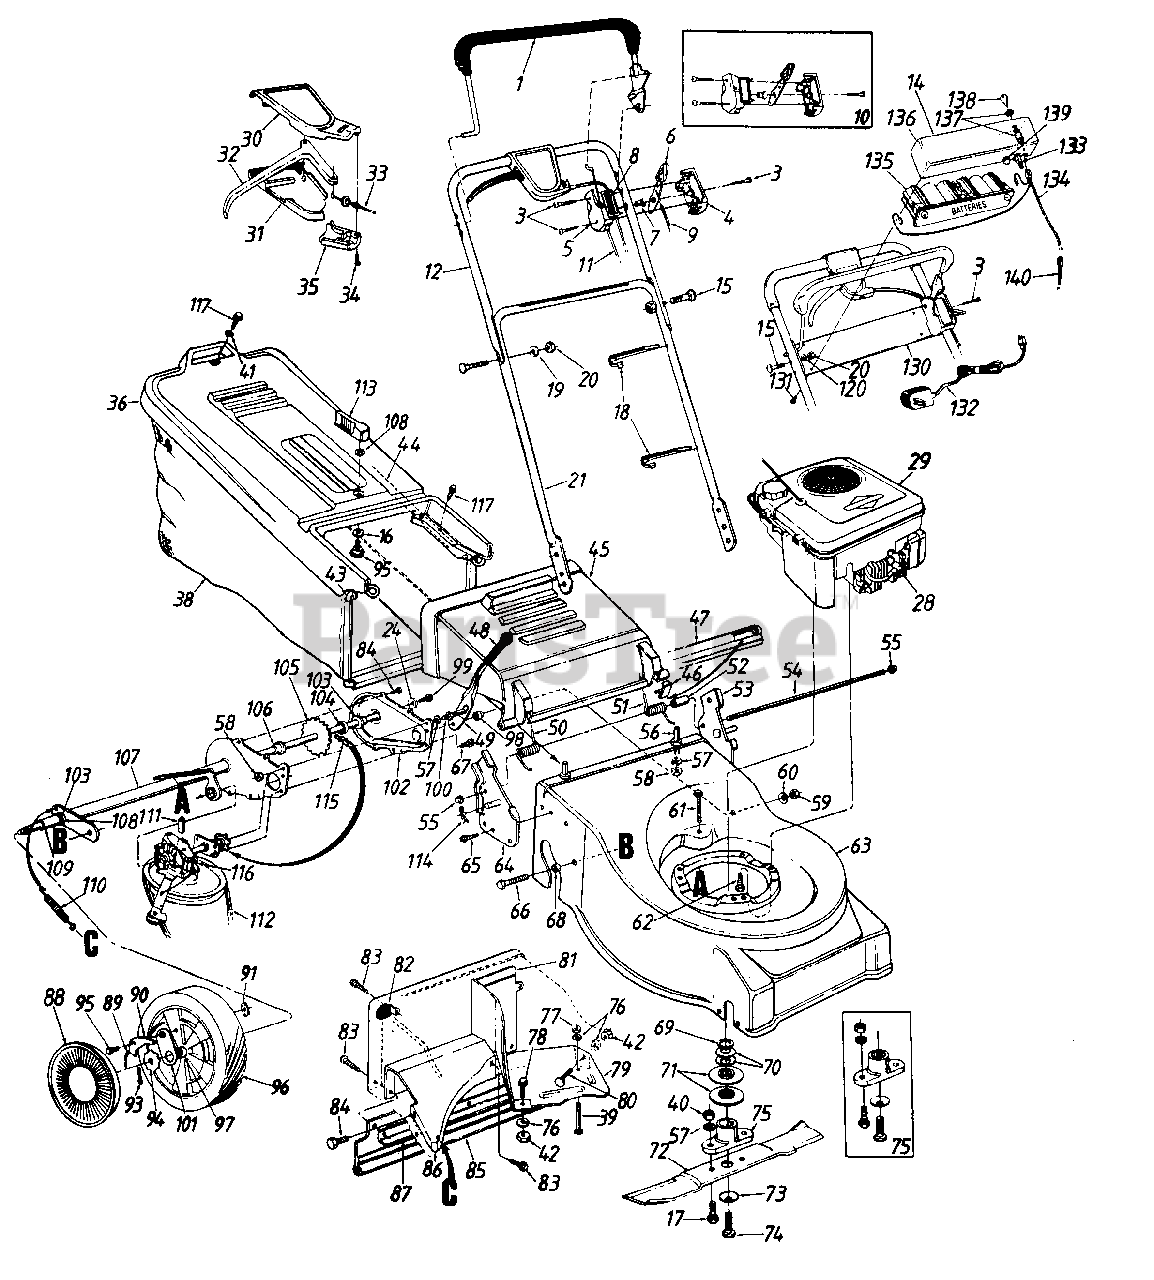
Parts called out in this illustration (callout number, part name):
1	Control Handle Ass'y.
3	Truss Mach. B-Tap Scr. #12 x 1.5" Lg.
4	Control Panel Half
5	Clutch Panel Half
6	Throttle Control Lever
7	Control Disc Pin
8	Control Label-Throttle
9	Throttle Wire-58" Lg.
10	Control Housing Comp.
11	Control Cable-43" Lg.
14	Instruction Label
15	Curved Carriage Bolt 5/16-18 x 1.38" Lg.
16	Bowed Washer
17	Hex Bolt 3/8-24 x 1" Lg.
18	Cable Tie
19	L-Wash. 5/16" I.D.*
20	Hex Nut 5/16-18 Thd.*
21	Lower Handle
24	Bell-Wash. .265" I.D. x .75"
28	Spark Plug Boot
29	Engine
30	Control Cover Half-Upper
31	Control Cover Half-Lower
32	Control Lever
33	Adj. Drive Cable-51" Lg.
34	Flat C-Sunk Hd. Tap Scr. #10 x .75" Lg.
35	Cable Mtg. Cap
36	Hardtop Bag Cover
38	Grass Ba9tt
39	Truss Mach. Scr. 1/4-20 x 1.0" Lg.
40	Hex Nut 3/8-24 Thd.
41	Fl-Wash. .281" I.D. x .62"
42	Hex Nut 1/4-20 Thd.*
44	Rear Catcher Frame
45	Chute Deflector
46	Deflector Plug
47	Seal-Extrusion
49	Spring Lever
50	Torsion Spring-R.H.
51	Torsion Spring-L.H.
52	Spacer.255" I.D.
53	Handle Brkt. Ass'y.-L.H.
54	Hinge Pin 17.75" Lg.
55	Cap Speed Nut
56	Shld. Pin 3/8-24 x 1.43" Lg.
57	L-Wash. 3/8" I.D.*
58	Hex Jam Nut 3/8-24 Thd.
59	Hex L-Nut 3/8-24 Thd.
60	Bell-Wash. .38" I.D. x .88"
61	Hex Wash. Hd. Tap Scr. 1/4-20 x 1.5" Lg.
62	Hex L-Wash. Hd. Scr. 3/8-16x 1" Lg.
63	638/N 21" Deck Ass'y.
64	Handle Brkt. Ass'y.-R.H.
65	Hex L-Wash. Hd. AB-Tap Scr. 1/4 x.62" Lg.
66	Hex Wash. Hd. Tap Scr. 3/8-16 x .75" Lg.
67	Hex Wash. Hd. Tap Scr. 1/4-20 x .5" Lg.
68	Spacer.383" I.D.
69	Serrated Washer 1.0" I.D.
70	Wave Washer 1.005" I.D.
71	Serrated Pulley Half
72	21" Blade
73	Bell-Wash. .46" I.D.
74	Hex Bolt 7/16-20 x 1.5" Lg. (Grade 5)
75	Blade Adapter Kit
76	L-Wash. 1/4" I.D.*
77	Hex Jam Nut 1/4-20 Thd.
78	Hex Bolt 1/4-20 x .85" Lg.
79	Rear Belt Baffle
80	Carr. Bolt 1/4-20 x .50" Lg.
83	Torx Mach. AB-Tap Scr. 1/4 x .62" Lg.
84	Hexl B-Tap Scr. 1/4 x .38" Lg.
85	Rear Flap
89	Plastic Spring
90	Pawl.345" I.D.
91	Weld Nut 1/4-20 Thd.
93	Cotter Pin 1/8" Dia.
94	Ratchet Wheel 1.62" O.D.
95	Shld. Bolt .342" Dia. x .268"
96	Wheel Ass'y. Comp.-Rear
97	Bearing 1/2" I.D.
98	Shld. Spacer. 50" Dia.
99	Hex Bolt 1/4-20 x .62" Lg. (Grade 5)
100	Shld. Pin 3/8-24 x 1.43" Lg.
101	Pawl Plate
104	Fl-Wash. .531" I.D. x .93"
105	Rear Axle Ass'y.
106	Hex Flange Bearing
109	Spacer. 513" I.D.
110	Extension Spring 3.8" Lg.
111	Spacer.325" I.D.
112	V-Belt
113	Grass Catcher Locking Knob
114	Internal Cotter Pin 5/16" Dia.
115	#48 Chain .50" Pitch x 30 Links
116	Transmission Comp.
117	Hex L-Wash. H.D. AB-Tap Scr. 1/4 x.62" Lg.
120	Bell-Wash. .345" I.D. x .88"
130	Lower Battery Tray
131	Hex AB-Tap Scr. 1.0" Lg.
132	Battery Charger
133	Plug
134	Wire Harness
135	12 Volt Battery
136	Upper Battery Tray
137	Key Switch
138	Key
139	Fuse Holder
140	Ext. Harness
